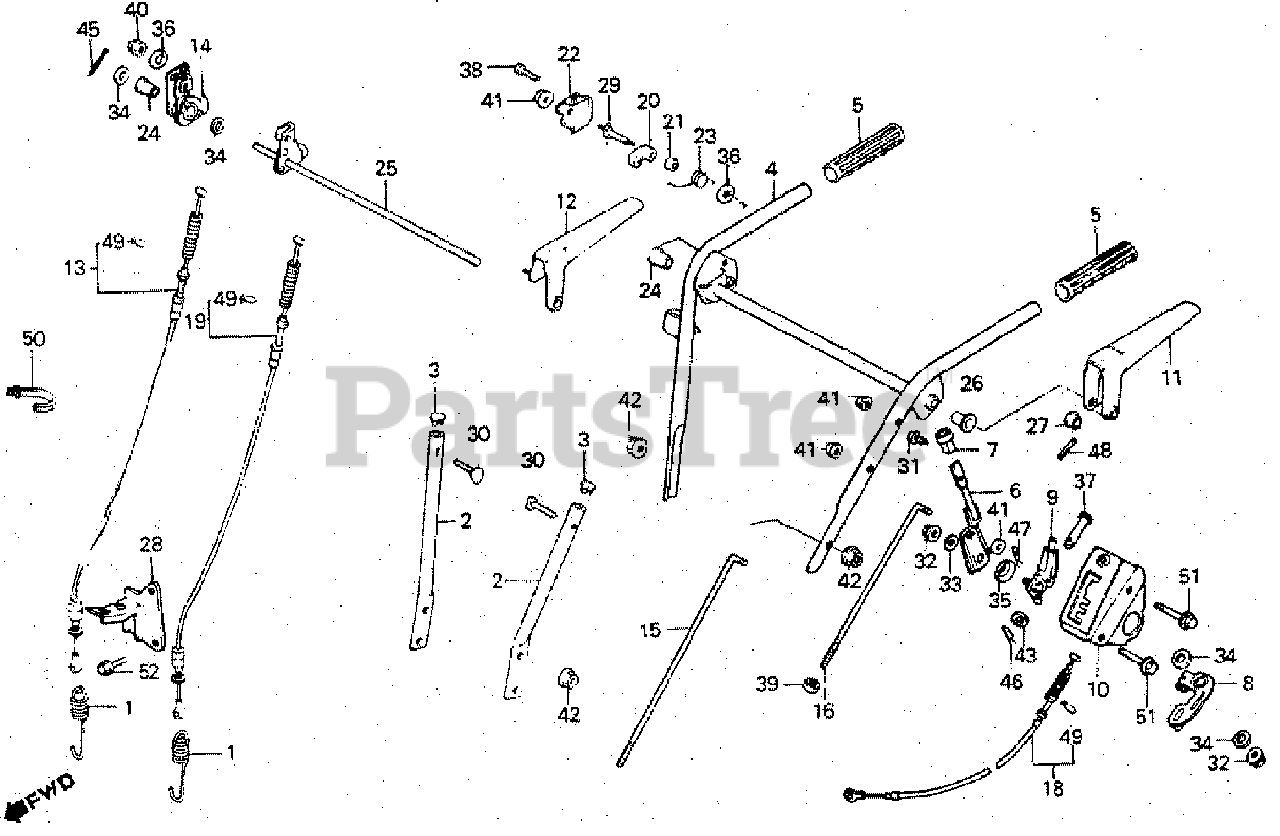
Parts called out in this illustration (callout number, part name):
1	SPRING, AUGER TENSION (NOT AVAILABLE)
2	HANDLE (LOWER)
3	CAP, HANDLE (LOWER)
4	PIPE, HANDLE (UPPER)
5	GRIP, HANDLE
6	LEVER, CHANGE
7	KNOB, LEVER
8	LINK, CHANGE
9	ARM, CHANGE LEVER
10	BRACKET, CHANGE LEVER
11	LEVER, CLUTCH
12	LEVER, AUGER CLUTCH
14	BOSS, CAM LOCK
15	ROD, GEARSHIFT
17	ROD, GEARSHIFT (NOT AVAILABLE)
18	CABLE, CHANGE (NOT AVAILABLE)
19	CABLE, CLUTCH
20	RATCHET, LEVER
21	COLLAR, RATCHET
22	COVER, RATCHET
23	SPRING, RATCHET
24	BUSH (13MM)
25	SHAFT, CLUTCH LEVER (NOT AVAILABLE)
26	BUSH (14MM)
27	BUSH (4.5MM)
28	HOLDER, AUGER WIRE
29	BOLT, PIVOT (6MM)
30	BOLT, HANDLE HOLDER
31	SCREW-WASHER, SPECIAL (4X8)
32	NUT, SELF-LOCK (8MM)
33	WASHER A (10MM)
34	WASHER (10MM)
35	SPRING, LEVER
36	WASHER (6MM)
38	BOLT, HEX. (6X6)
39	NUT, HEX. (8MM)
40	NUT, CAP (6MM)
41	NUT, FLANGE (6MM)
42	NUT, FLANGE (8MM)
43	WASHER, PLAIN (6MM)
44	WASHER, PLAIN (8MM)
45	PIN, COTTER (3.0X18)
46	PIN, LOCK (6MM)
47	PIN, LOCK (8MM)
48	PIN, SPRING (3X16)
49	CLIP, TUBE (B8)
50	BAND A2, CABLE
51	BOLT, FLANGE (6X35)
52	BOLT, FLANGE (8X16)
